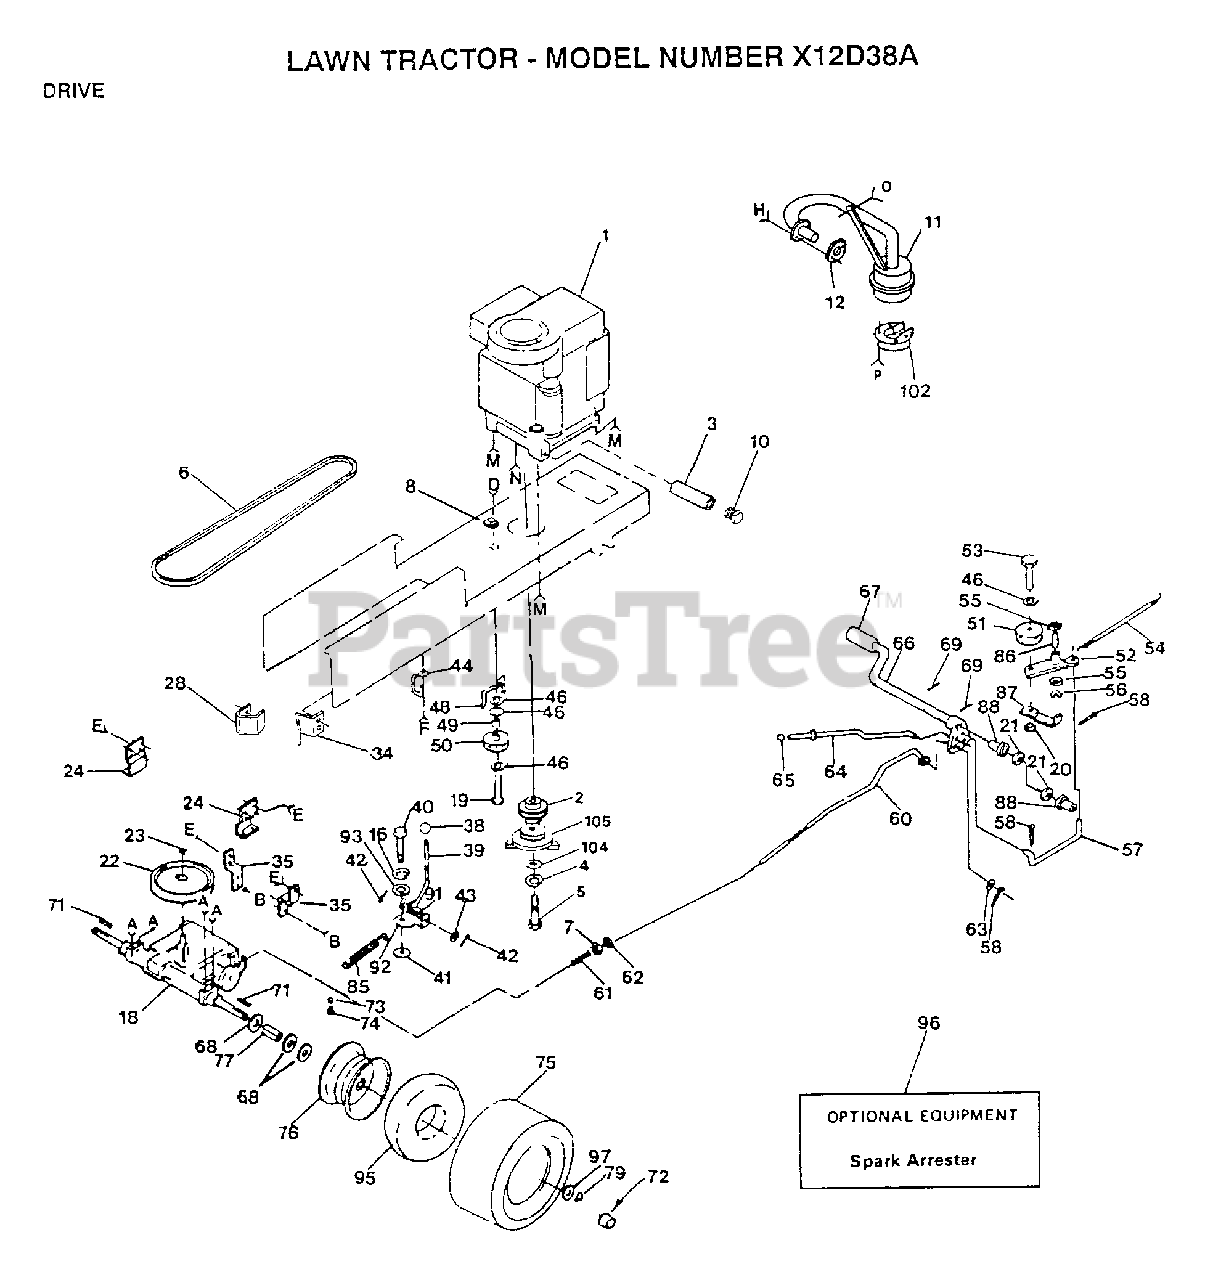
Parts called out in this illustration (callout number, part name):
1	ENGINE, 12HP, B&S
4	LOCKWASHER
5	BOLT
6	BELT-V.90.0.GD.DR
7	NUT
8	CLIP T
11	MUFFLER
16	LOCKWASHER
19	BOLT
21	WASHER LT
22	PULLEY TRANS
24	BRACKET LT
28	"KEEPER,BELT LH T"
34	"KEEPER,BELT RH T"
35	STRAP TORQUE
38	KNOB T (1/2-HOLE)
39	ROD SHIFTER
41	WASH-SHFT PLT LT
42	PIN COTTER 1/8
43	WASHER
46	WASHER
48	BELT KEEPER LT
49	SPACER T
50	PULLEY.IDLER.FLAT
52	ARM IDLER
54	"SPRING, RETURN LT"
55	WASHER LT
56	KLIP RING
57	"LINK, CLUTCH T"
58	COTTER PIN
60	BRAKE ROD LT
61	SPRING ROD LT
62	NUT
63	WASHER
65	PLUNGER CAP T
67	PEDAL COVER T
68	WASHER
71	SQUARE KEY
72	HUB CAP
73	VALVE CAP
74	VALVE STEM LT
75	TIRE.TS2.18X8.5
77	SPACER LT
79	E-RING LT
86	"LY, BEARING"
87	RETAIN BELT
88	NYLON BEARING
91	SPRING LT
92	PLATE SHIFT LT
93	WASHER LT
95	TUBE.18X9.5-8
96	SPARK ARREST KIT
97	WASHER
102	DEFLECTOR.222573
